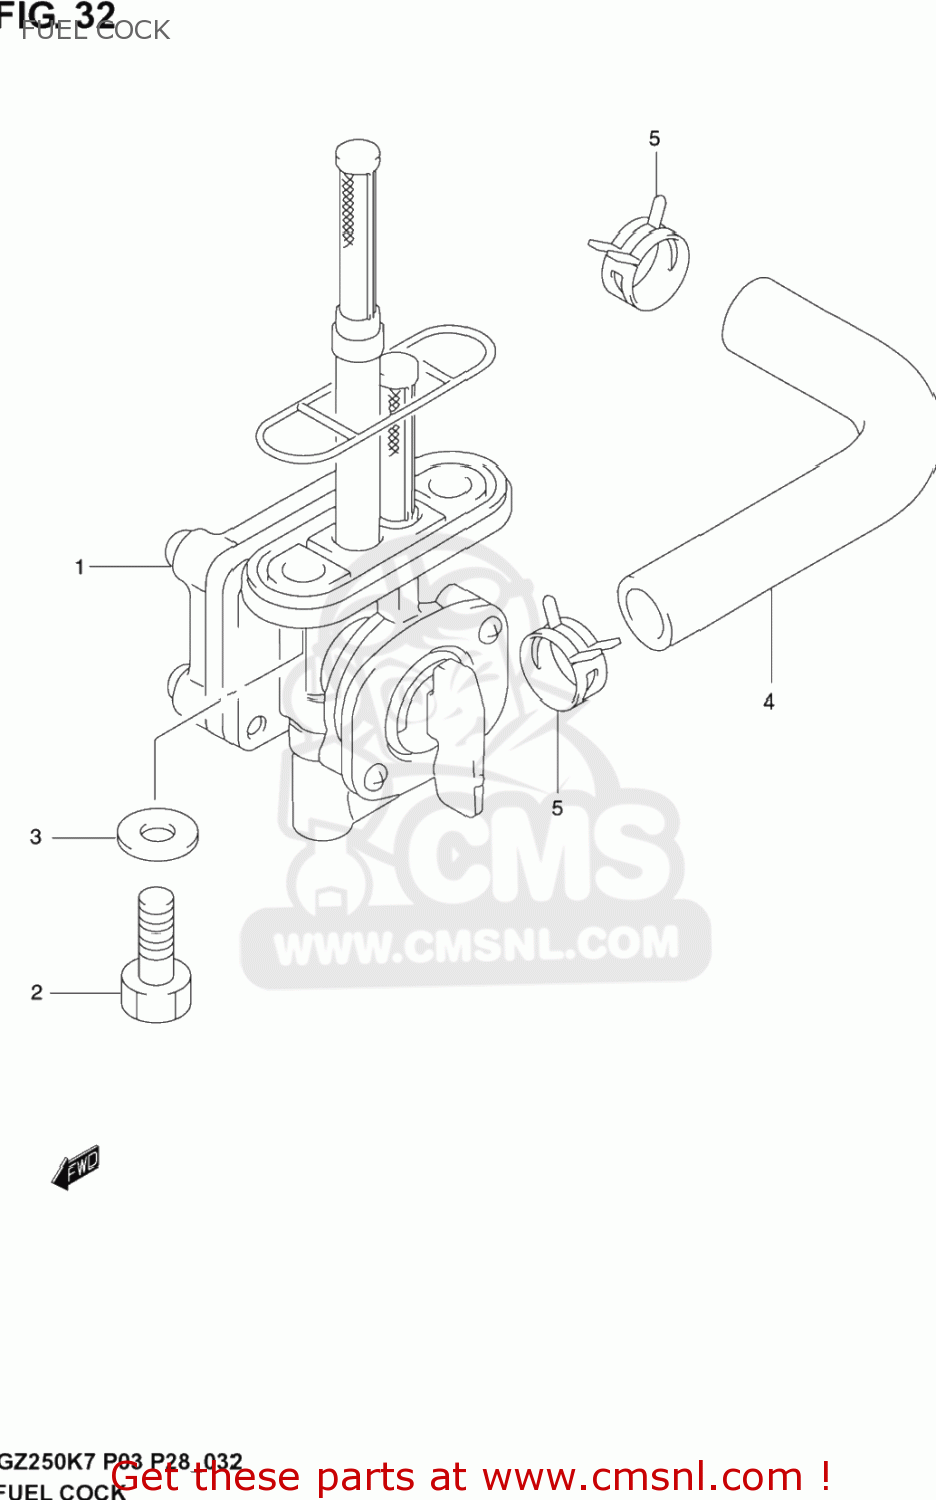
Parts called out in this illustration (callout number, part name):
1	COCK ASSY,FUEL
2	BOLT(6X20)
3	GASKET(6.4X11.5X0.8) (NAS)
4	HOSE(7X12X600)
5	CLIP
